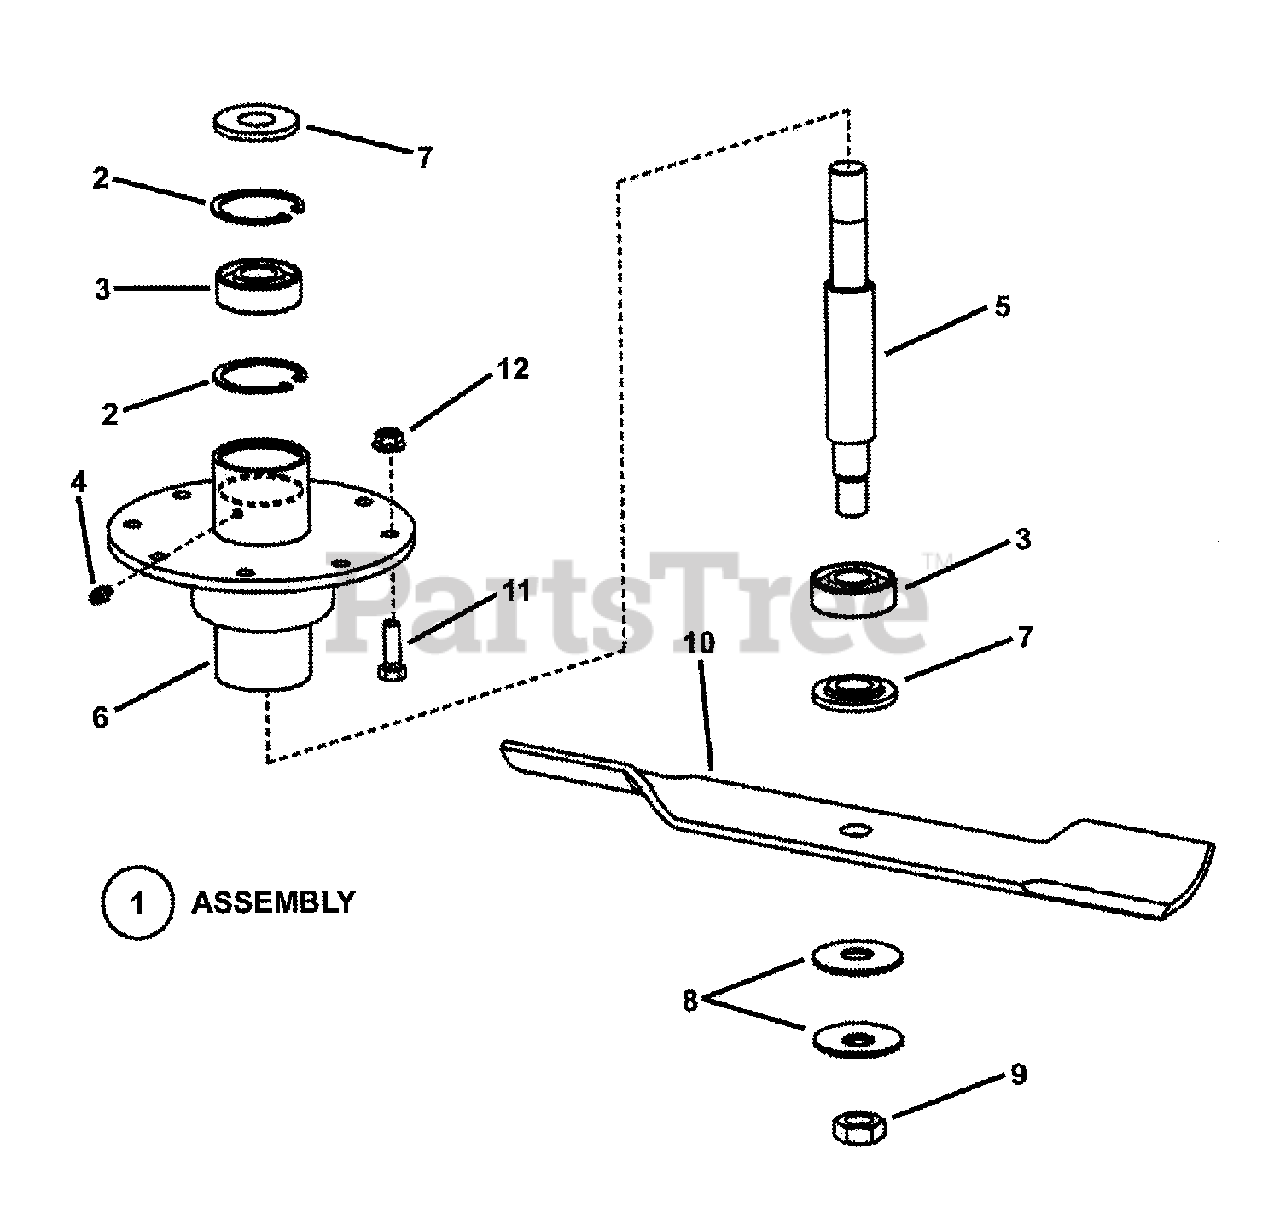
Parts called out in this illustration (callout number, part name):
1	ASSEMBLY, 48" Spindle
2	RING, 1-3/4" External Retaining Ring
3	BALL BEARING, 3/4" I.D.
4	FITTING, Lube, Press-In (for .187 dia. Hole)
5	SHAFT, Spindle (7.81" long)
6	WELDMENT, 48" Spindle
7	WASHER, Spindle
8	WASHER, .656 Belleville
9	NUT, 5/8-18 Hex Jam
10	BLADE, 16-1/2" Low Inertia
11	SCREW, 5/16-18 x 1" Hex Head Cap, GR 5
12	NUT, 5/16-18 Hex Flange Lock, GR 5
